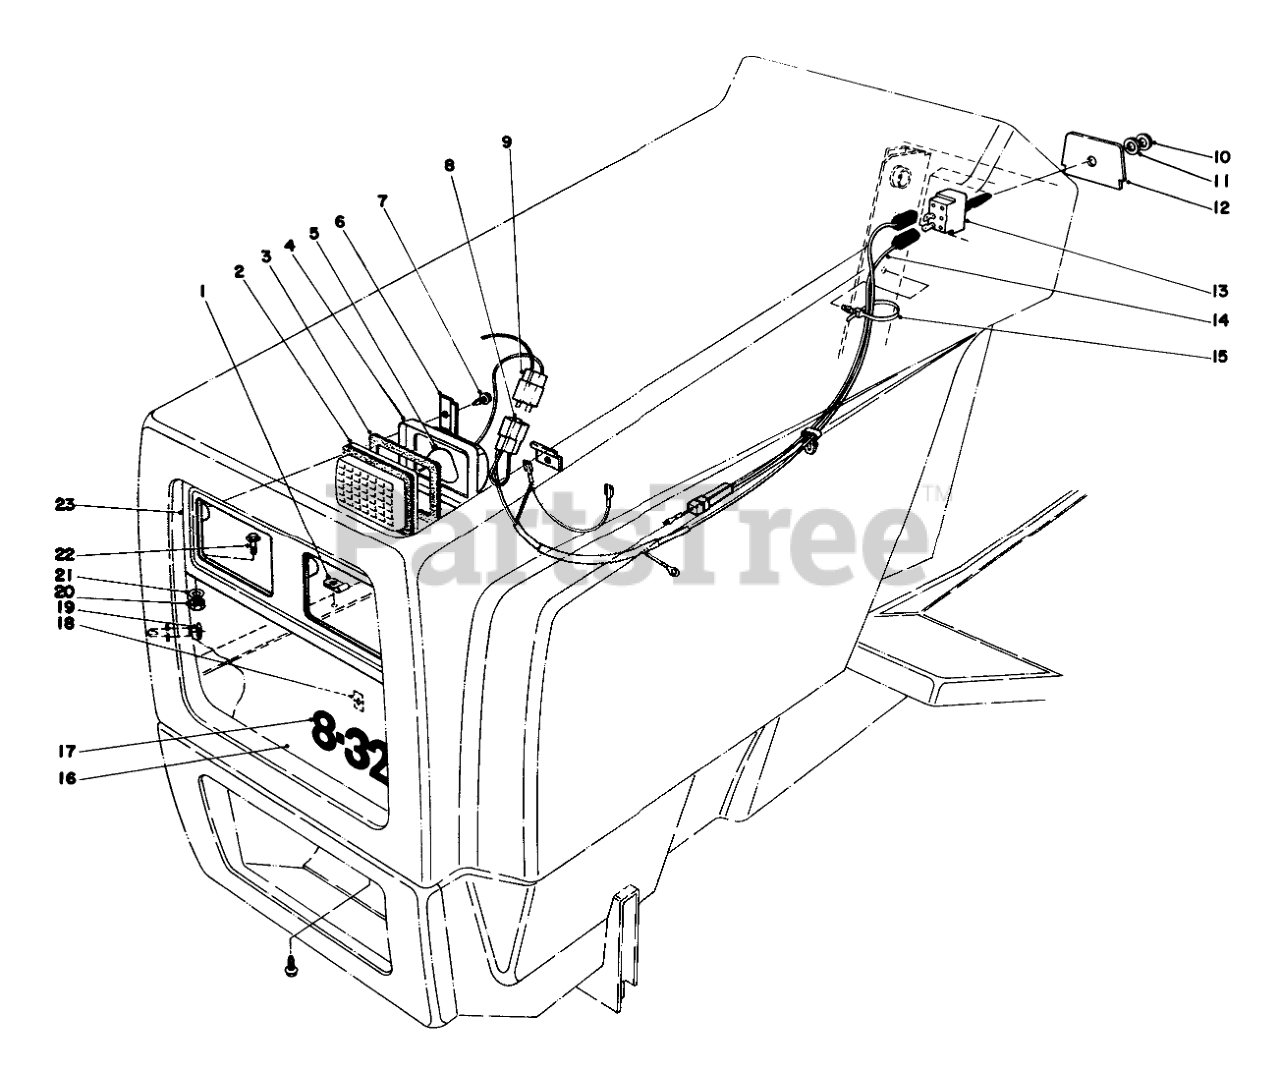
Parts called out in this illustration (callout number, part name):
1	CABLE CLAMP
2	Lens
3	Gasket Lens
4	Reflector Assembly
6	HEADLIGHT CLAMP
7	SCREW-HWHTF
8	Connector
9	SOCKET
10	Facenut
11	Locknut
12	DASH PANEL INSERT
13	110 Light Switch
14	WIRE HARNESS
15	TIE-CABLE
16	HEADLIGHT GRILLE
17	Nameplate Grille
19	WASHER
20	NUT-LOCK, SIDE
21	WASHER-FLAT
22	SCREW-SHWH
23	HEADLIGHT PANEL B
